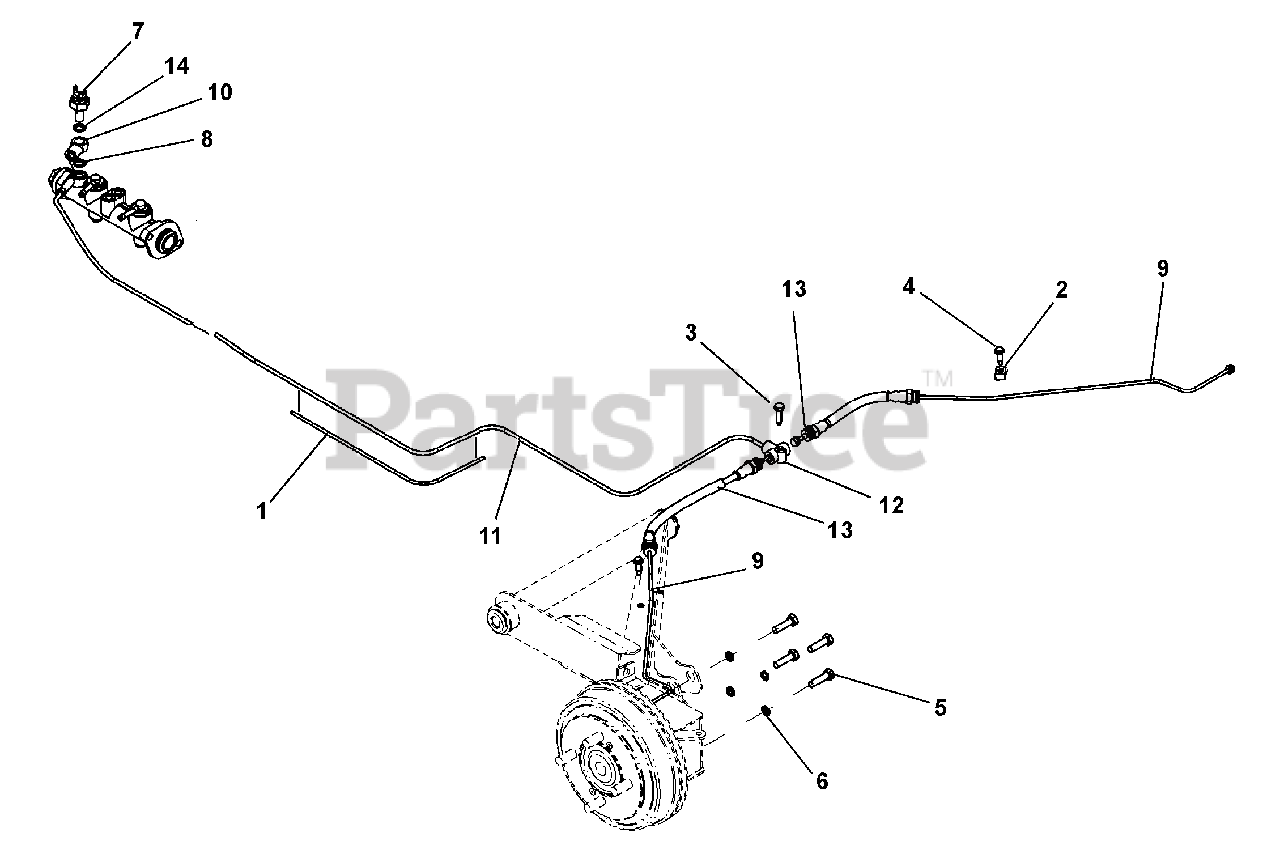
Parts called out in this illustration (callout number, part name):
1	CORRUGATED LOOM, .125 ID
2	WIRING/TUBE CLIP FOR 1/4 OD
3	SCREW HHC SELF TAP 1/4-20 X 1
4	HH DRILL SCREW 1/4 X 3/4 LG
5	HHCS M8X1.25 X 30 GR10.9 ZNYCR
6	WASHER LOCK M8 YWZC
7	BRAKE SWITCH, HIGH PRESSURE
8	WASHER, COPPER, 3.5 MM
9	REAR BRAKE LINE 28.3
10	BULK HEAD FLOW THROUGH
11	ST STEEL BRAKE LINE
12	FITTING 3 WAY HYD.
13	REAR RUBBER BRAKE LINE
14	MSTR CYL CPPR WSHR 16 X 10 X 1.5 MM
